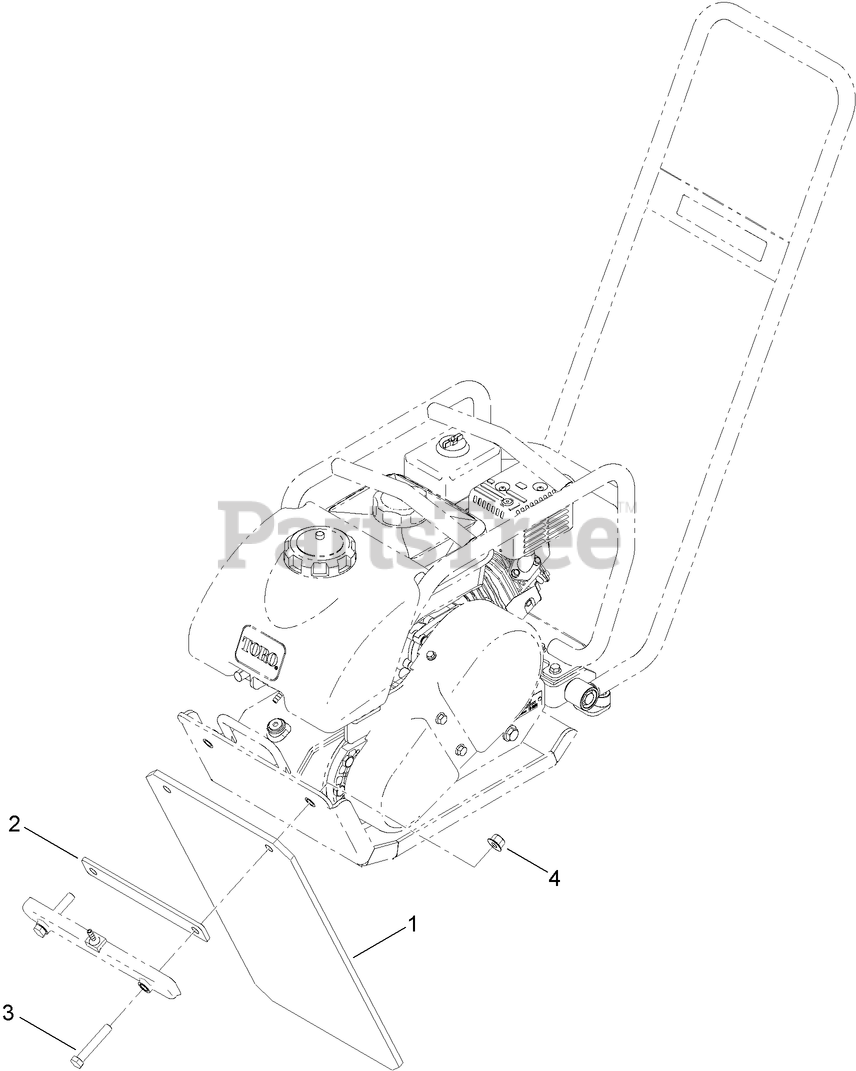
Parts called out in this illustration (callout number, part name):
1	MAT-PAVER
2	CLAMP-PAVER
3	SCREW-HH
4	NUT-LOCK, HHF
